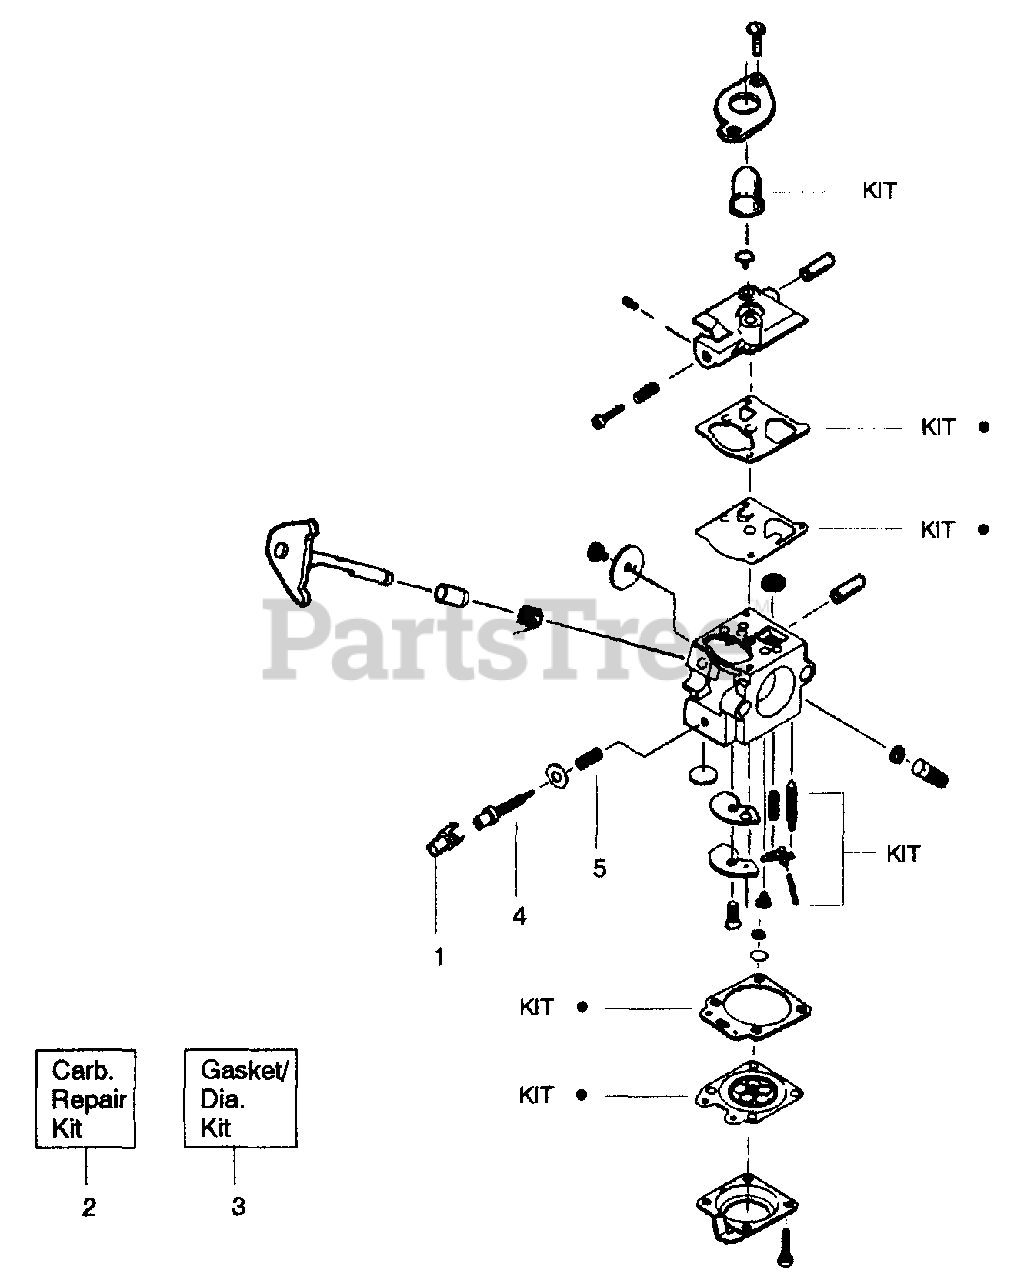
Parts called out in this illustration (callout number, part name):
1	Limiter Cap
2	Carburetor Repair Kit
3	Gasket Diaphragm Kit
4	Needle - Idle
5	Spring - Idle Needle
